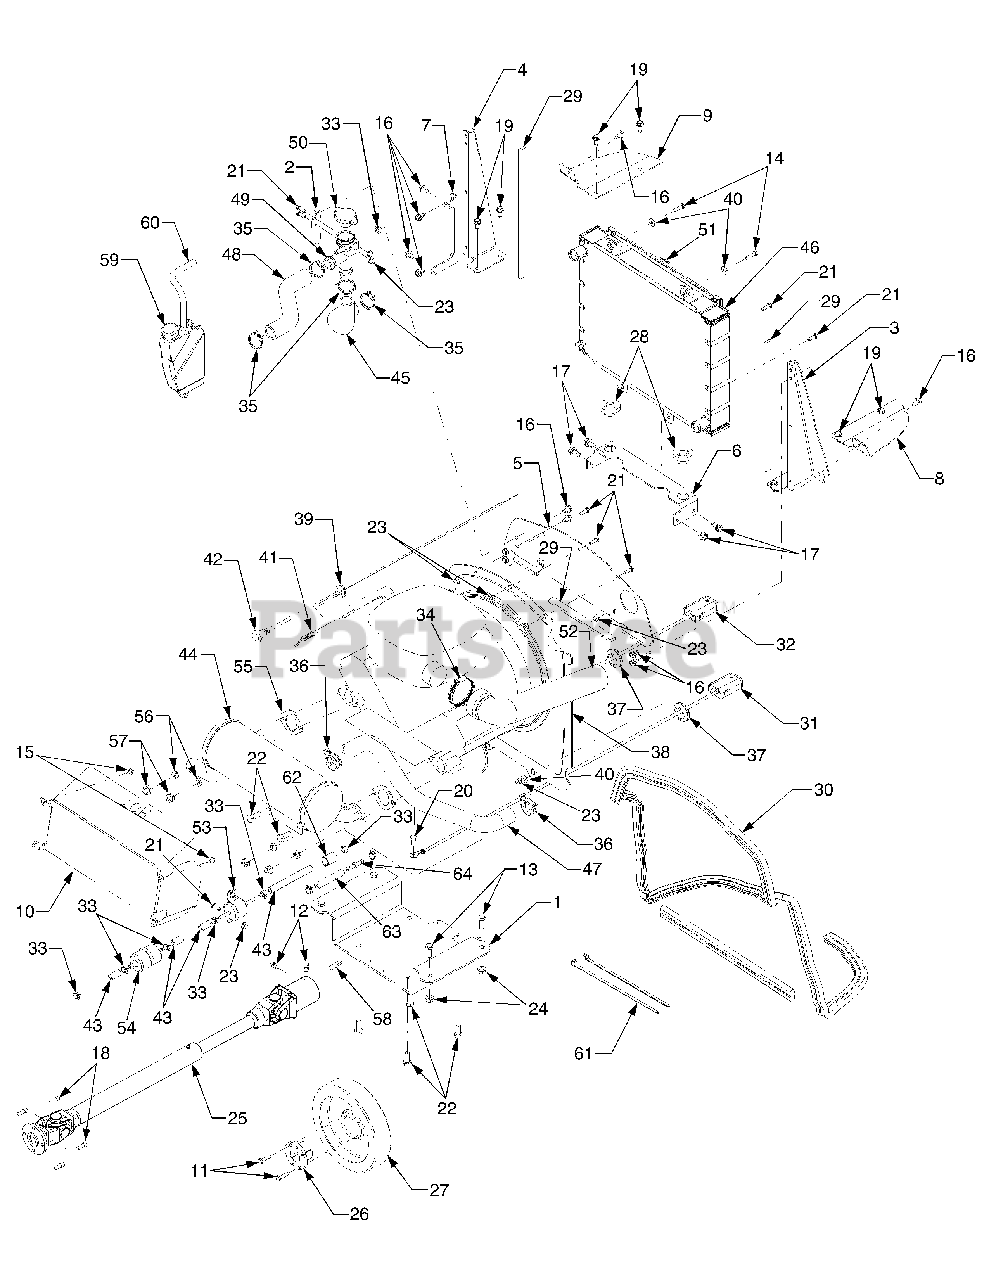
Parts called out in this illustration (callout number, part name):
3	Bracket, Radiator Mtg. RH
4	Bracket, Radiator Mtg. LH .
5	Plate, Radiator Baffle
6	Bracket, Radiator Mtg.
7	Bracket, Ovrflw Bottle Mtg.
11	Screw, Hex Cap, 1/4-28 x 1.0 GR5
12	Screw, Square Hd. Set, 3/8-16
13	Screw, Hex Cap, 3/8-16 x 1.0 GR5
14	Screw, Hex Cap, 1/4-20 x 1.0 GR5
15	Screw, Hex Wash Hd Tapp 1/4-20 x .5
16	Screw, Hex Wash Hd Tapp 5/16-18 x .5
17	Screw, Hex Wash Hd Tapp 3/8-16 x .75
18	Screw, Socket Hd Cap, 1/4-20 x .62 GR8
19	Screw, Hex Wash Hd Tapp 5/16-18 x .75
20	Screw, Hex Cap, M8-20 x 16 GR8.8
21	Screw, Hex Cap, 1/4-20 x .75 GR5
22	Screw, Hex Cap, M10 x 1.5 x 25 GR5
23	Nut, Hex Insert Flange Lock 1/4-20 GrF
24	Nut, Hx Insert Flange Lock, 3/8-16 GrF
25	Shaft, Drive
26	Bushing, D Type
27	Flywheel
28	Grommet, Rubber
29	Tape, Foam, .625 wide 42in.
30	Seal, Heat Baffle 103in.
31	Wire, Battery Neg.
32	Wire, Battery Pos.
33	Clamp, Hose
34	Clamp, Hose - Adjustable .
35	Clamp, Hose
36	Clamp, Hose
38	Shroud, Fan
40	Washer, Flat,. 28 x .74 x .063
41	Cable, Throttle
42	Cable, Choke Control
43	Fuel Line 5/16 ID 92in.
45	Hose, Filler to Radiator
47	Hose, Lower Radiator
48	Hose, Engine to Filler Neck
49	Filler Neck, Remote Radiator
50	Cap, Remote Filler
51	Screen, Radiator
52	Hose, Intake Air
54	Filter, Fuel
55	Gasket, Exhaust
56	Washer, Spring
58	Key, Crankshaft
59	Bottle, Over Flow
61	Tie, Cable
62	Sleeve, Fuel Line Reflective
63	Fuel Line, 1/4 Return 65in.
64	Fitting, Fuel Restrictor: 2mm
